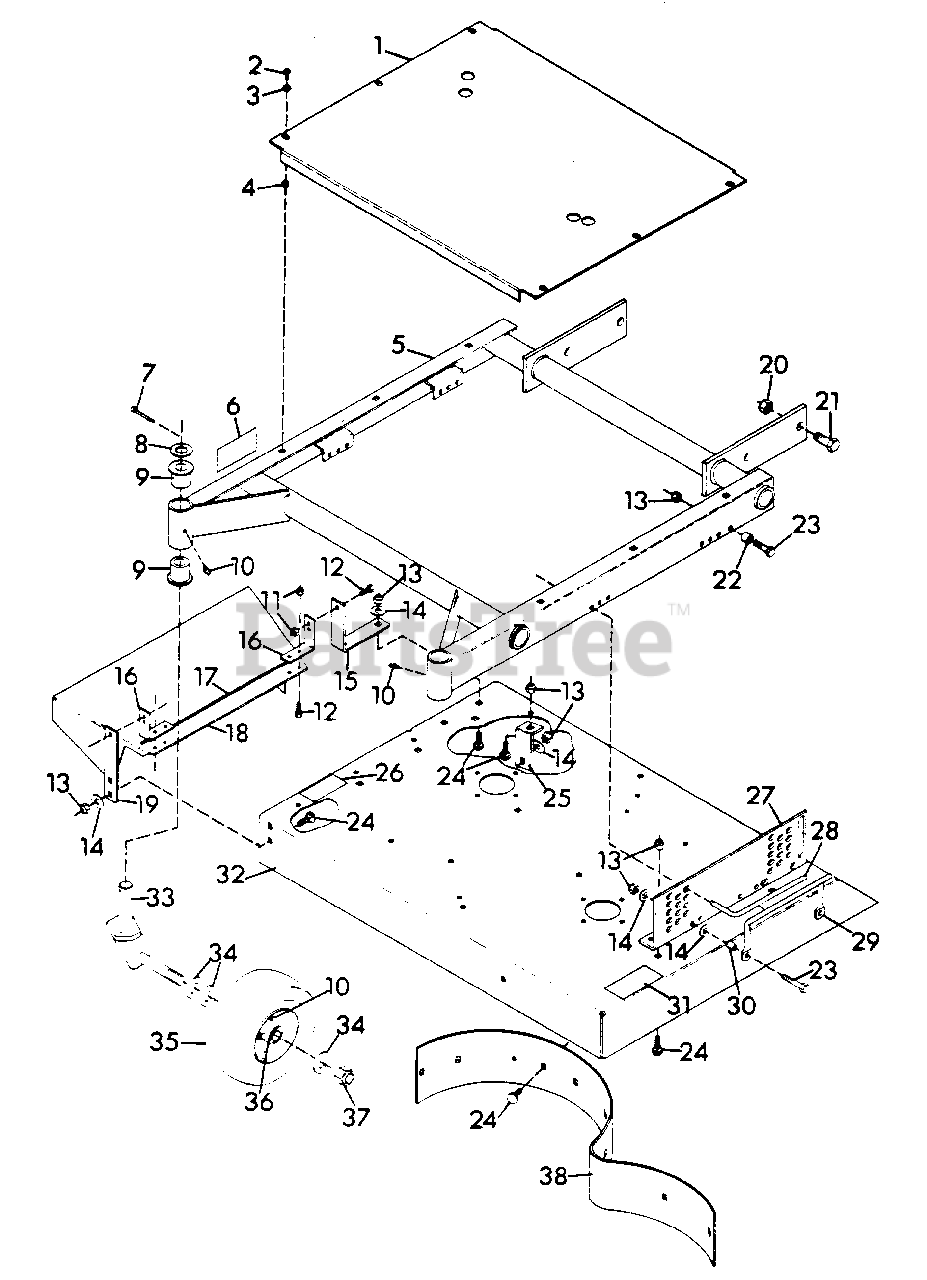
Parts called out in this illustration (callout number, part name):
1	Cover, Silkscreen 36" Mower
2	Screw, Tapping 1/4-20x.625 P/Hd
3	Washer, Flat .281x.625x.065
4	Grommet, Plastic
5	Weldment, Mower Frame
6	Decal, Danger Hand
7	Pin, Cotter .187x1.50
8	Race, Bearing Thrust
9	Bushing, Pivot
10	Fitting, Lube 1/4-28
11	Nut, Lock 5/16-18
12	Bolt, Hex 5/16-18x.75
13	Nut, Lock 3/8-16
14	Washer, Flat .406x.812x.065
15	Bracket
16	Bracket
17	Stripe
18	Chute, Discharge
19	Bracket
20	Nut, Lock 5/8-11
21	Bolt, Hex 5/8-11x1.50
22	Bushing .391x.622x.670
23	Bolt, Hex 3/8-16x1.50
24	Bolt, 3/8-16x1.00 Rd Hd Sq Nk
25	Bracket
26	Decal, Warning Eye
27	Bracket, Mower Side Support L.H.
27	Bracket, Mower Side Support R.H.
28	Pin, Mower Locking
29	Handle
30	Bushing
31	Decal, Danger Foot
32	Weldment, 36" R.D. Deck
33	Weldment, Caster Fork
34	Washer, Flat .812x1.496x.134
35	Wheel, Gauge
36	Bearing, Gauge Wheel
37	Nut, Lock 3/4-10
38	Scroll
